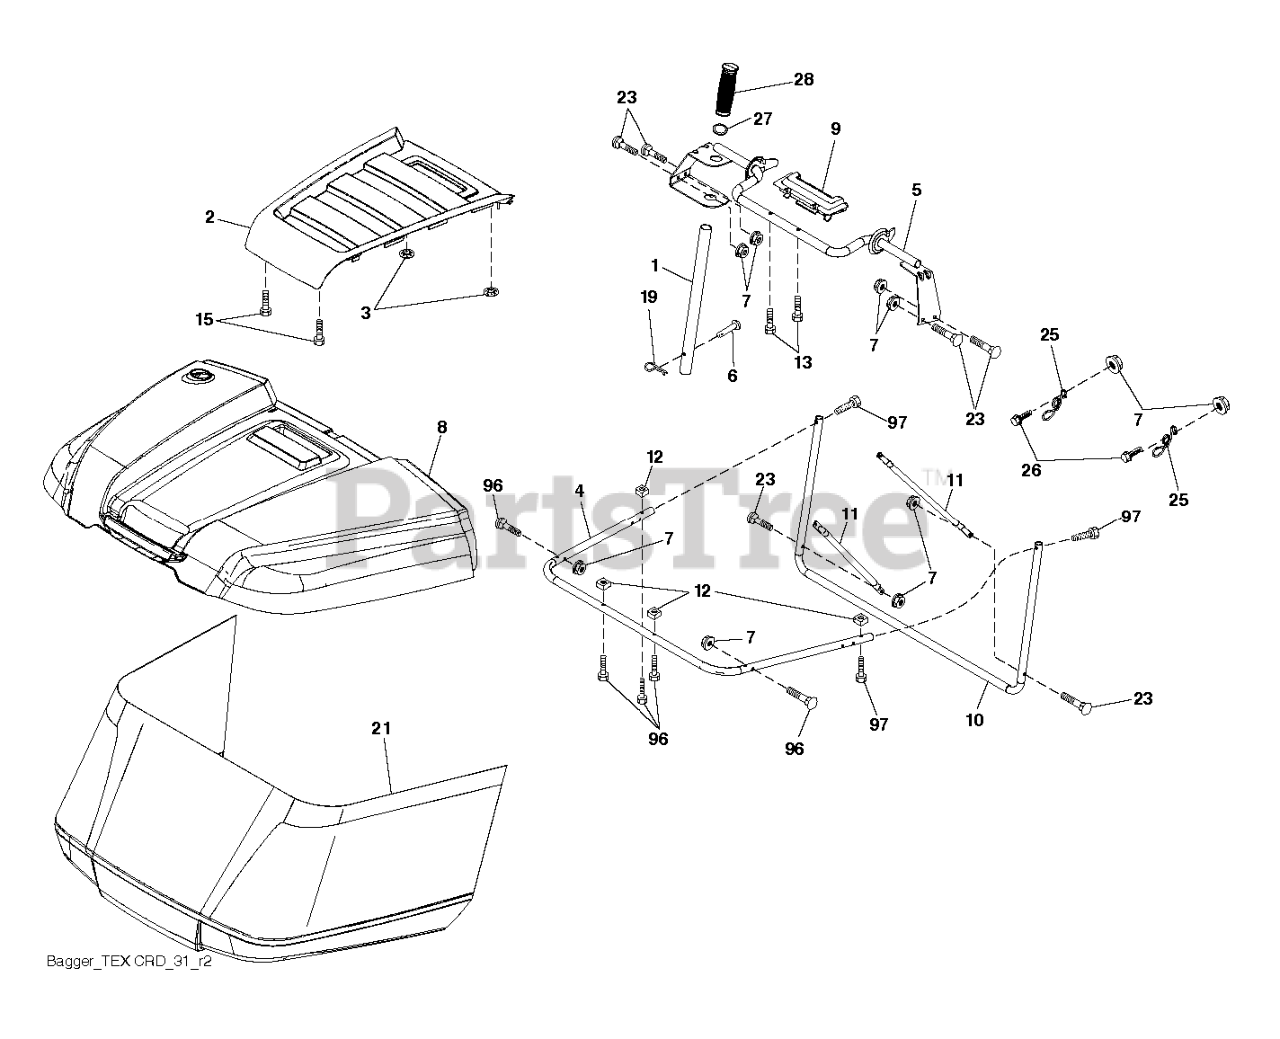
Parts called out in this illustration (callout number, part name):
1	TUBE.HANDLE.BAGGER.CRD/SRD.BLA
2	APPLIQUE.TOP.BAG.SRD.ORANGE
3	NUT.PUSH.156
4	SUBASM.TOP.BAGGER.TUBE
5	FRAME.ASM.TOP.BAGGER.SRD
6	RIVET,DRILLED
7	NUT T
8	BAGGER.TOP.SRD.APPLIQUE
9	INSERT.HANDLE.BAGGER.(2 2)
10	FRAME FRAME.FRONT.TEX.CRD
11	BRACE BRACE SIDE TUBE
12	NUT.SQUARE.1/4
13	SCREW.1/4X1.150.HXWSH
15	SCREW,#8.FLAT.HEAD.DRILL.TIP
19	PIN.COTTER.5/16.BOW TI
21	BAG SUBASM. TEX CRD GEN 2 HUSQ
25	SPRING.LATCH.BAGGER.SRD
26	SCREW HEX CRT
27	RB GROMMET.RUBBER.SRD
28	GRIP.HANDLE.BLACK
96	SCREW.HEXCAP.1/4X-20X1.500
97	SCREW.TORX.BUTN.HD.1/4-20-1.5"
